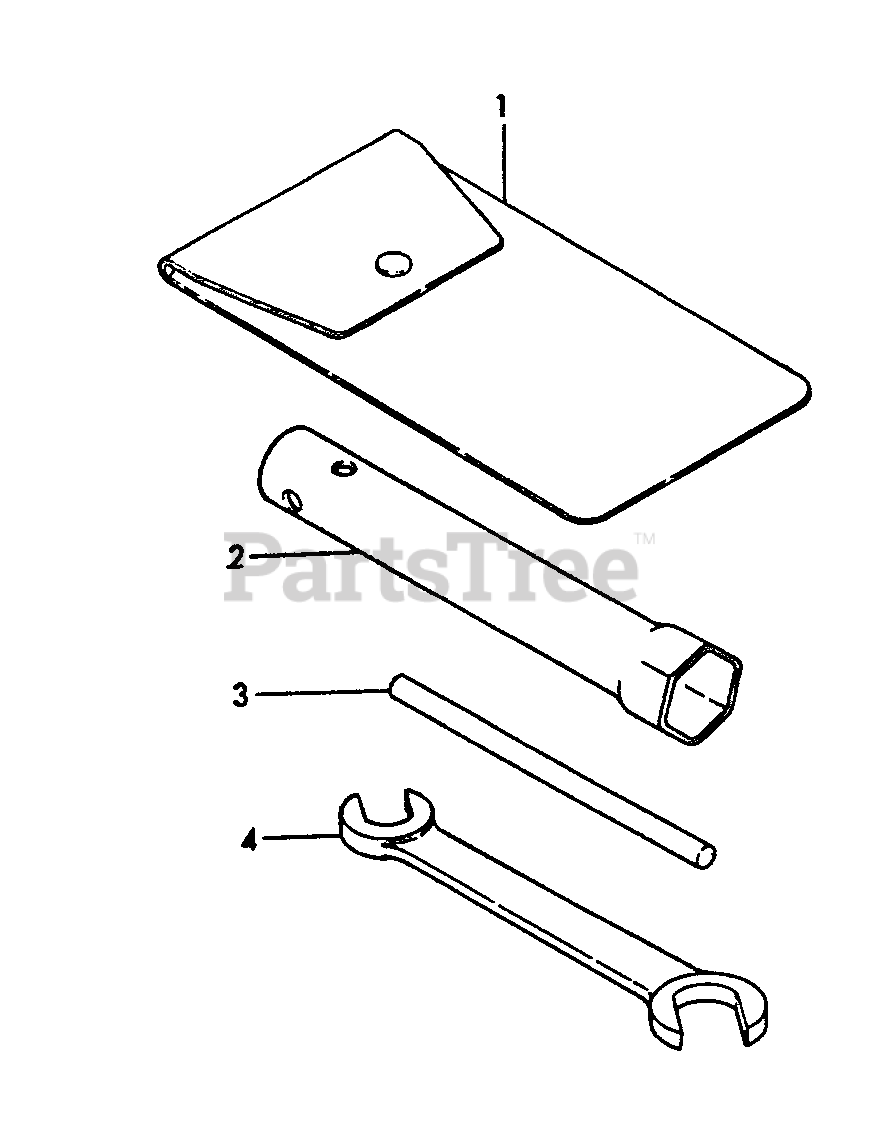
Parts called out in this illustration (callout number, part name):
1	BAG, TOOL
2	SOCKET WRENCH - 21mm
3	BAR
4	SPANNER - 10X12mm
